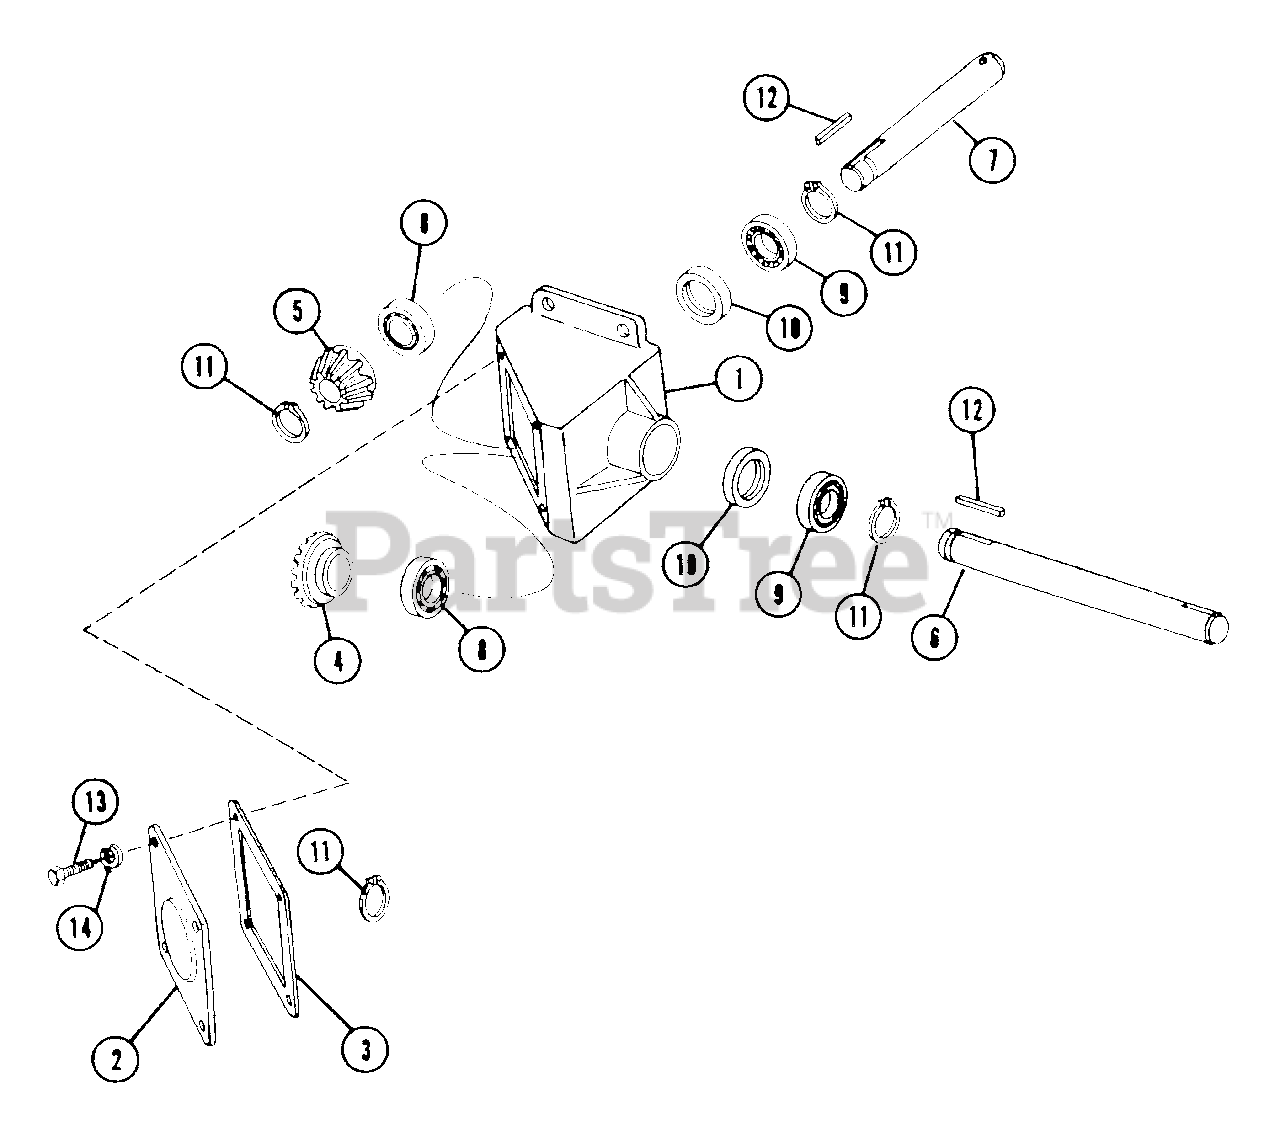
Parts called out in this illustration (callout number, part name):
1	GEARBOX HOUSING
2	GEAR BOX LID
4	BEVEL GEAR OUTPUT
5	BEVEL GEAR INPUT
6	OUTPUT SHAFT
7	INPUT SHAFT
8	BRG-BALL .750X1.625X.31
9	BRG-BALL .750X1.625X.50
10	SEAL .750X1.624X.312
11	RG-RTNG-EXT .750X.042
12	KEY-SQ .188X.68X.188 DANUSER
13	BLT-HEX .25-20X.50 PL GR2
14	WSHR-LK .250X.077 HVY PL
